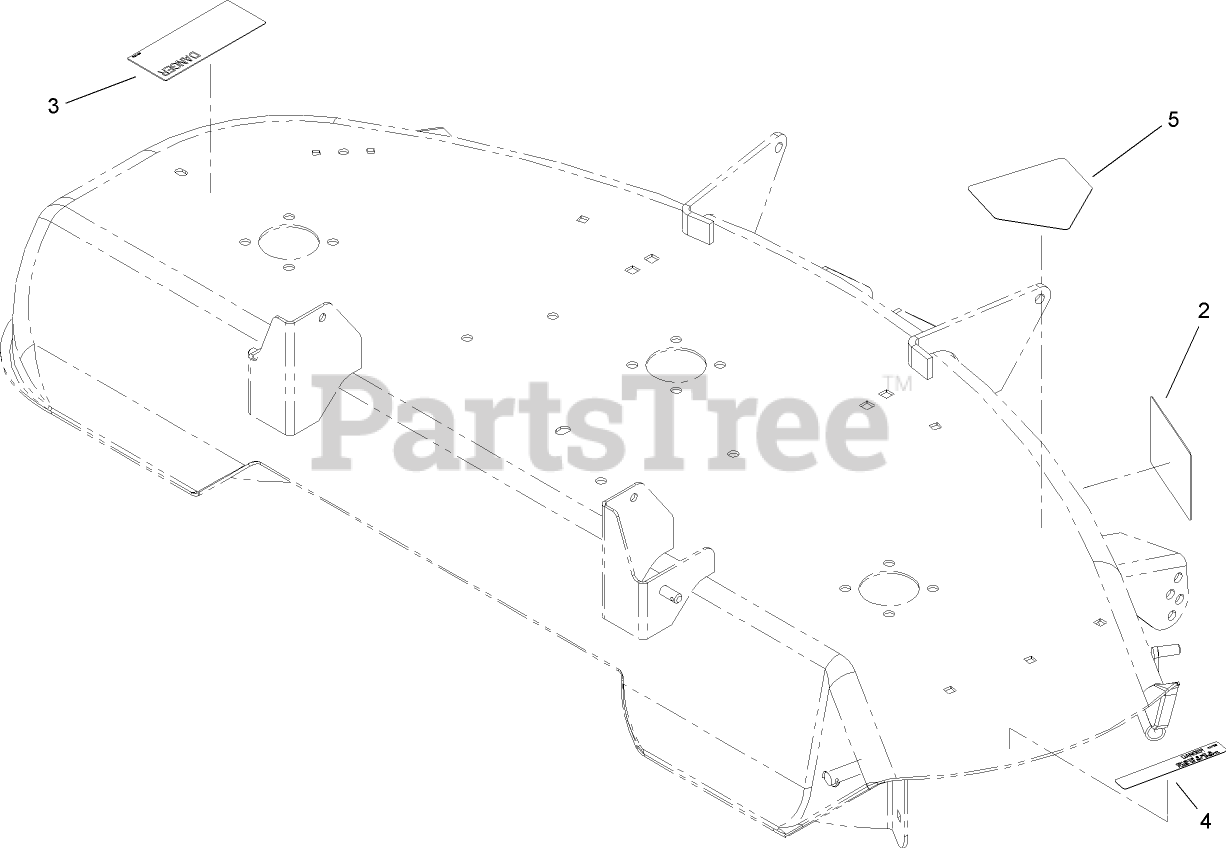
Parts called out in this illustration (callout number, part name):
2	DECAL-ANTI SCALP
3	DECAL-DANGER
4	DECAL-DANGER
5	DECAL-DANGER, SHIELD
